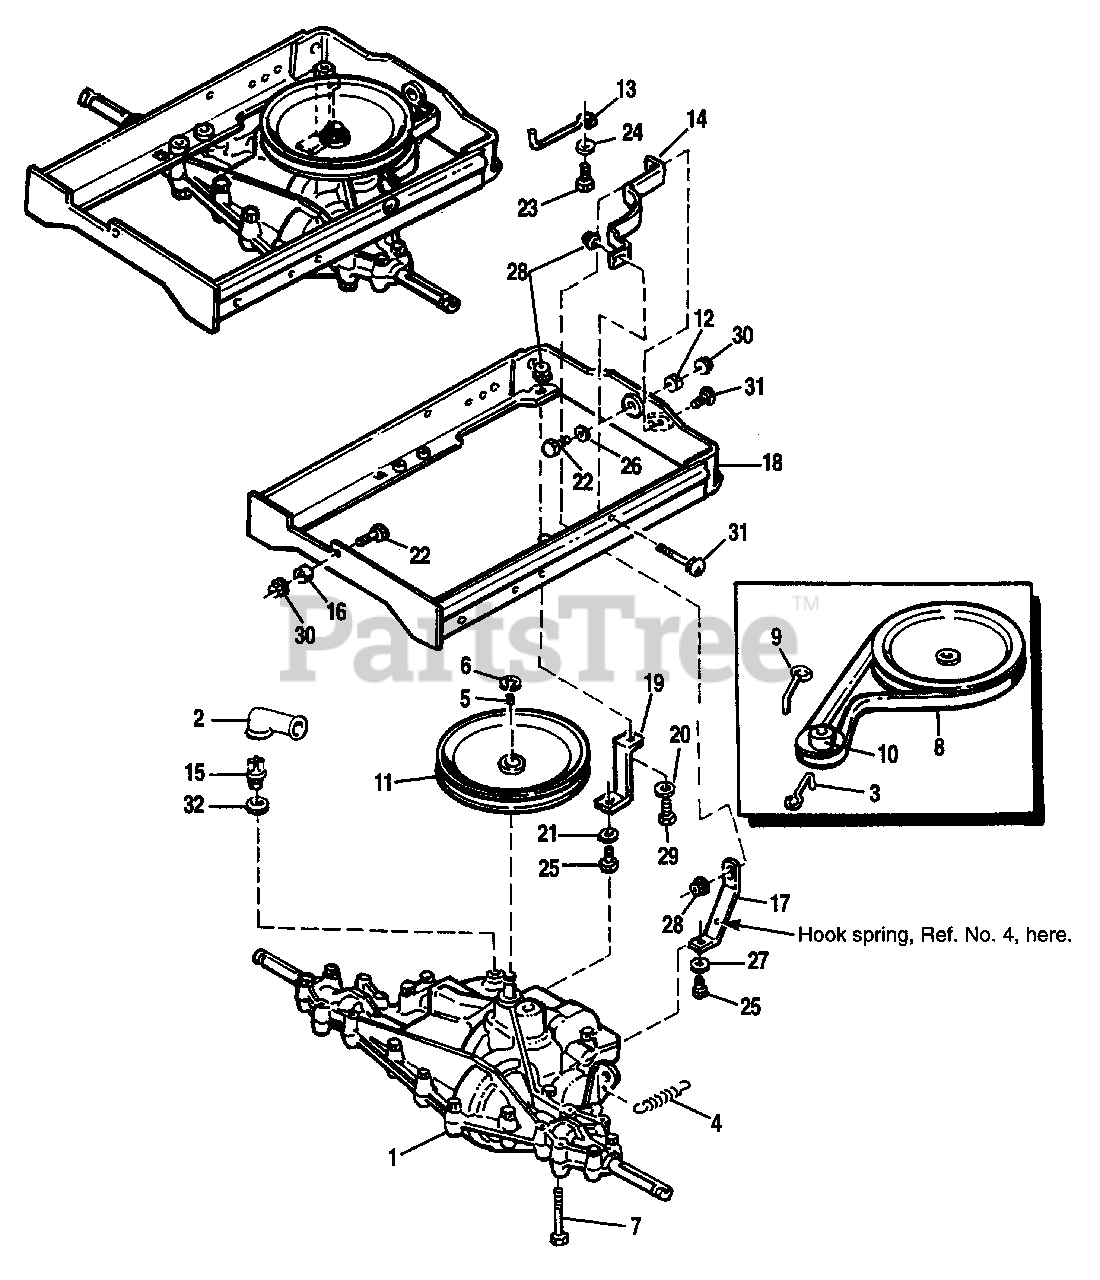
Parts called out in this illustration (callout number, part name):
1	TRANSMISSION, 5-Speed (Gear)
2	COVER, Terminal
4	SPRING, Return
5	KEY, Woodruff, #9
6	RING, Retaining
7	SCREW, Hex Hd., 5/16-18 x 2-1/4
10	PULLEY ASSY., Drive, Engine
11	PULLEY ASSY., Driven, Transmission
12	BUSHING, Rear
13	BELT STOP
14	GUIDE, Belt, Transmission
15	SWITCH, Ball
16	BUSHING, Front
17	STRAP, Torque
18	CARRIER ASSY.
19	STRAP, Torque
20	WASHER, Plain, 5/16
21	WASHER, Plain, 7/16 x 1-1/4 x 1/8
22	CAPSCREW, Hex Hd., 1/2-13 x 1-1/4
23	CAPSCREW, Hex Hd., 3/8-16 x 1-3/4
24	WASHER, Plain, 13/32 x 1 x 1/8
25	SCREW, Hex Hd., Taptite, 3/8-18 x 5/8
26	WASHER
27	WASHER, Plain, 13/32 x 7/8 x 5/64
28	NUT, Hex, Flange, Whizlock, 5/16-18
29	SCREW, Hex, Flange, Whizlock, 5/16-18 x 3/4
30	NUT, Hex, Flange Lock, 1/2 x 13
31	CARRIAGE BOLT, 5/16-18 x 5/8
32	WASHER, Plain, 21/32 x 1-1/4 x 1/16
